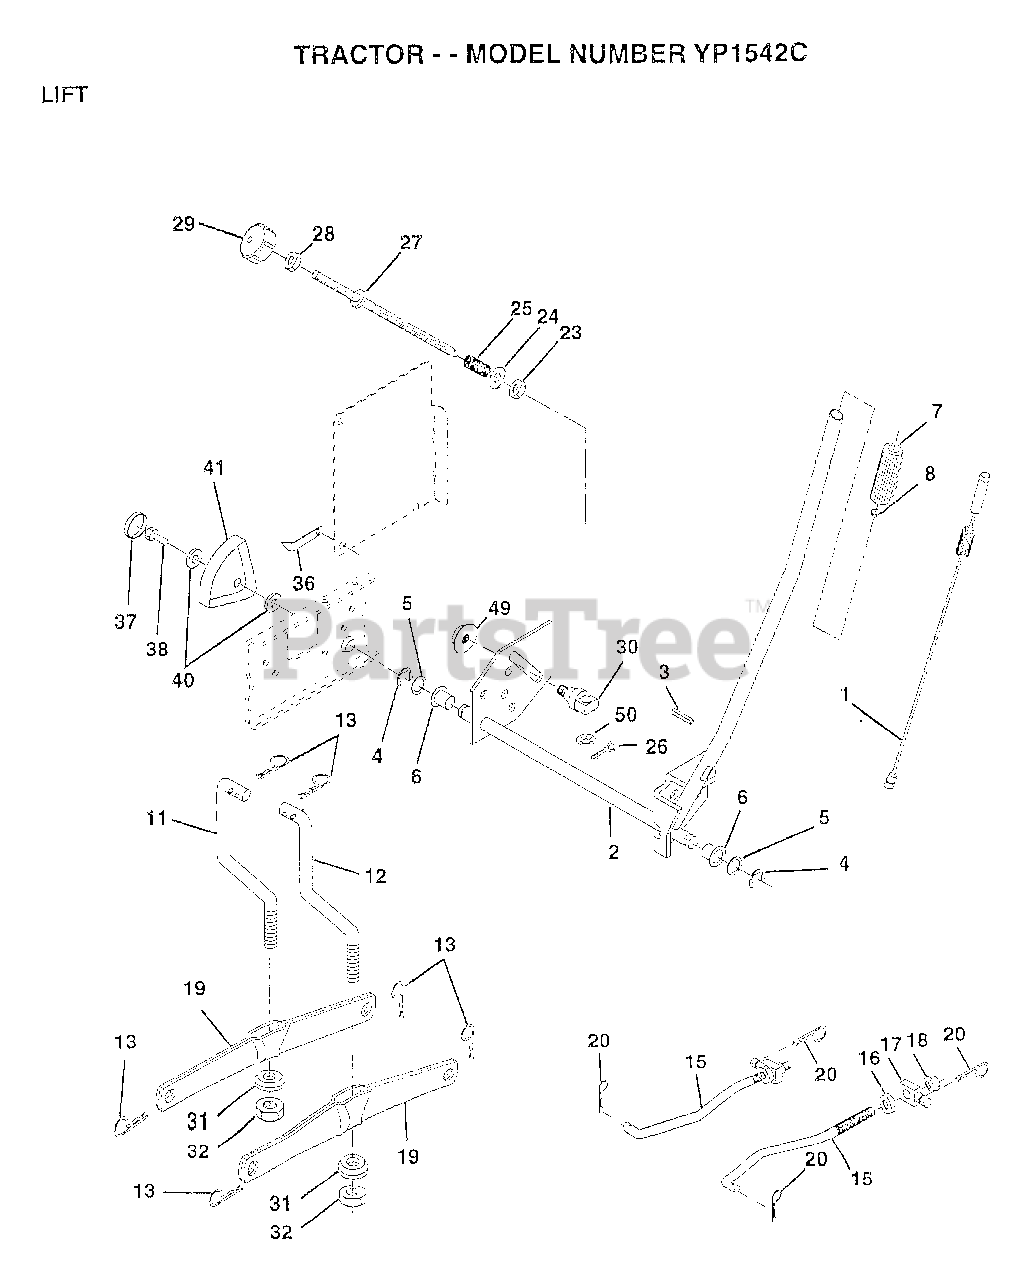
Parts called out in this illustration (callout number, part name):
1	WIRE ASM W.SPRING
2	"SHAFT ASM LIFT,RH"
3	PIN-GROOVE LT
5	WASHER
6	NYLON BEARING
7	GRIP HANDLE
15	LINK.FRONT
16	NUT
17	TRUNION
18	NUT.LK.W/WSH.1/2.
19	ARM SUSP REAR
20	RETAINER SPRING
23	NUT T
24	WASHER
25	SPRING T
28	NUT
29	KNOB INF 3/8-16
30	TRUNNION
31	BEARING PVT LH
32	NUT.CROWNLOCK.3/8
36	POINTER-INDICAT
37	"PLUG,HOLE"
38	SCREW
40	WASHER
41	HEIGHT INDICATOR
49	NUT.HXFLG.LOCK.
50	NUT PUSH M
